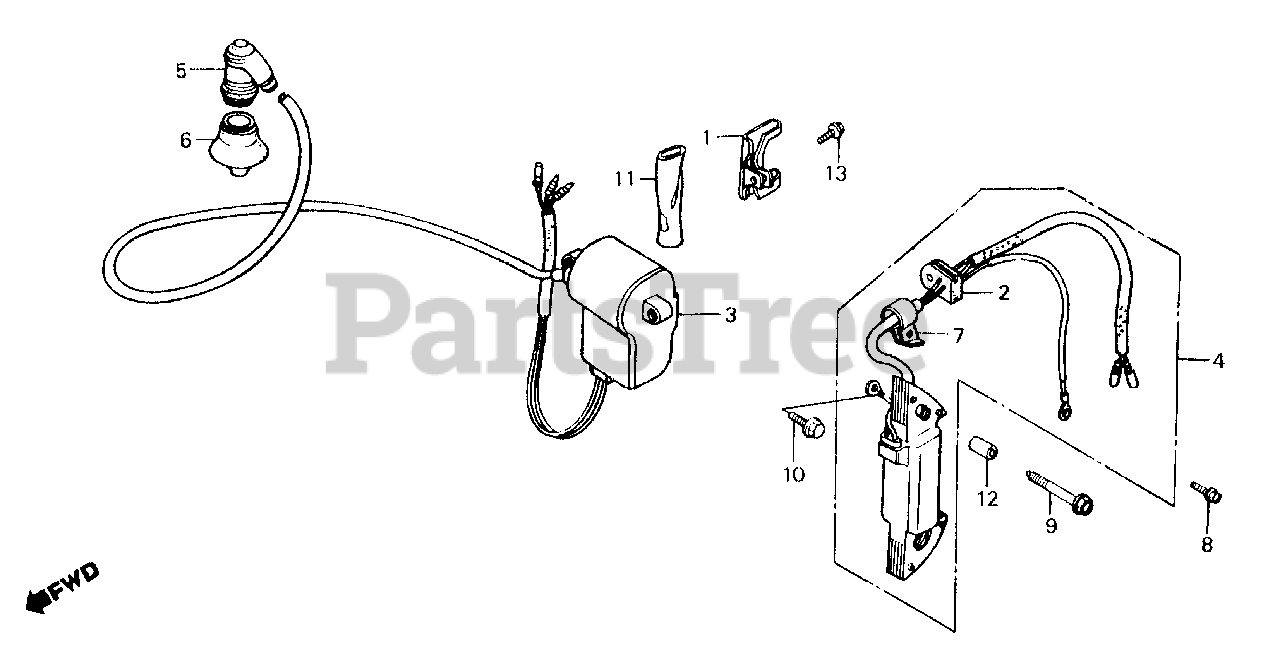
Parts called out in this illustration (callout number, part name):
1	CLIP, WIRE
2	GROMMET, WIRE
3	MODULE, IGNITION CONTROL (CDI) (NOT AVAILABLE)
4	COIL ASSY., EXCITER (NOT AVAILABLE)
5	CAP ASSY., NOISE SUPPRESSOR
6	SEAL, IGNITION
7	CLAMP, IGNITION WIRE
8	BOLT, FLANGE (6X12) (CT200)
9	BOLT, FLANGE (6X28)
10	BOLT, FLANGE (5X10)
11	TUBE, WIRE
12	PIN A, DOWEL (8X14)
13	BOLT, FLANGE (6X12)
